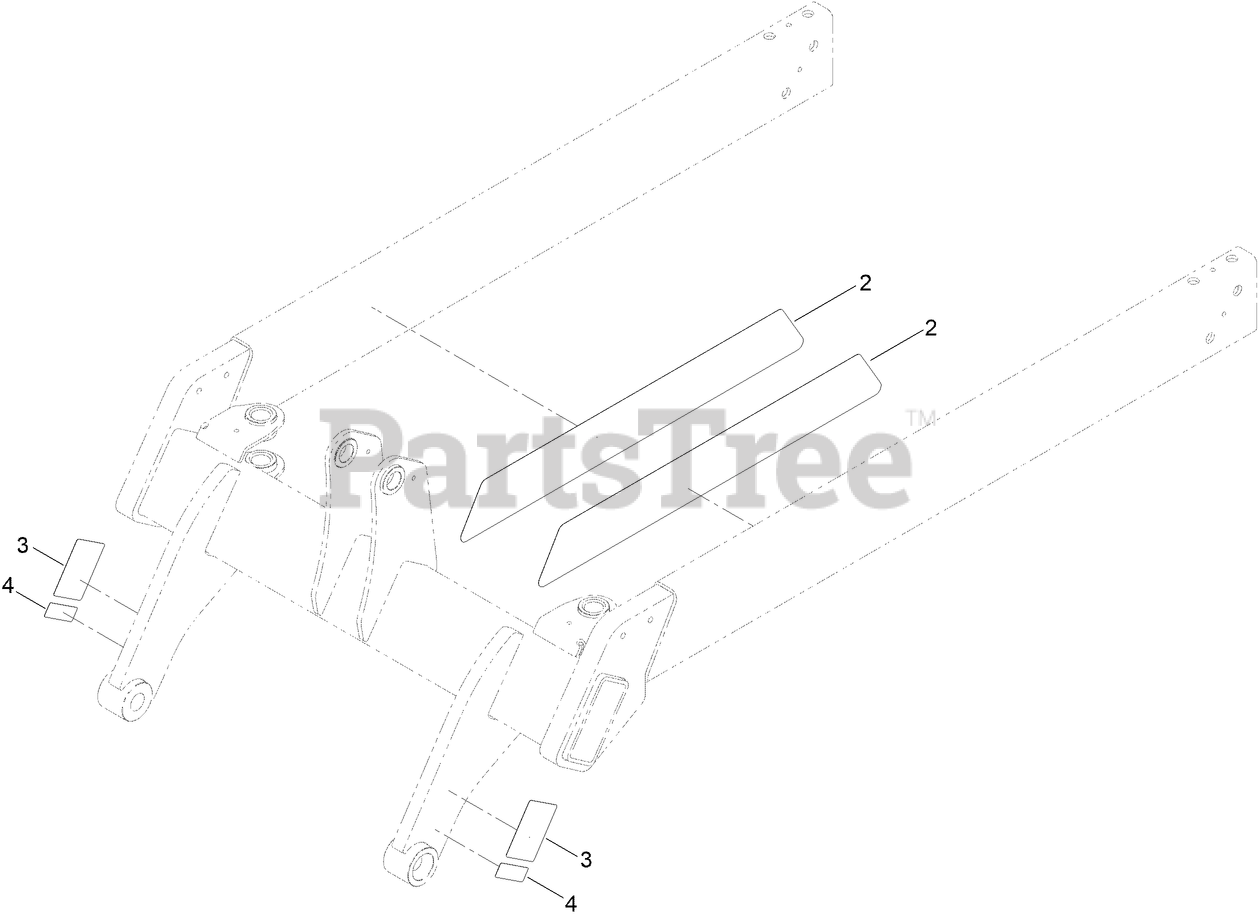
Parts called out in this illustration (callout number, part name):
2	DECAL-EXTENSION
3	DECAL-WARNING, BUCKET
4	DECAL-WARNING, PINCH POINT
